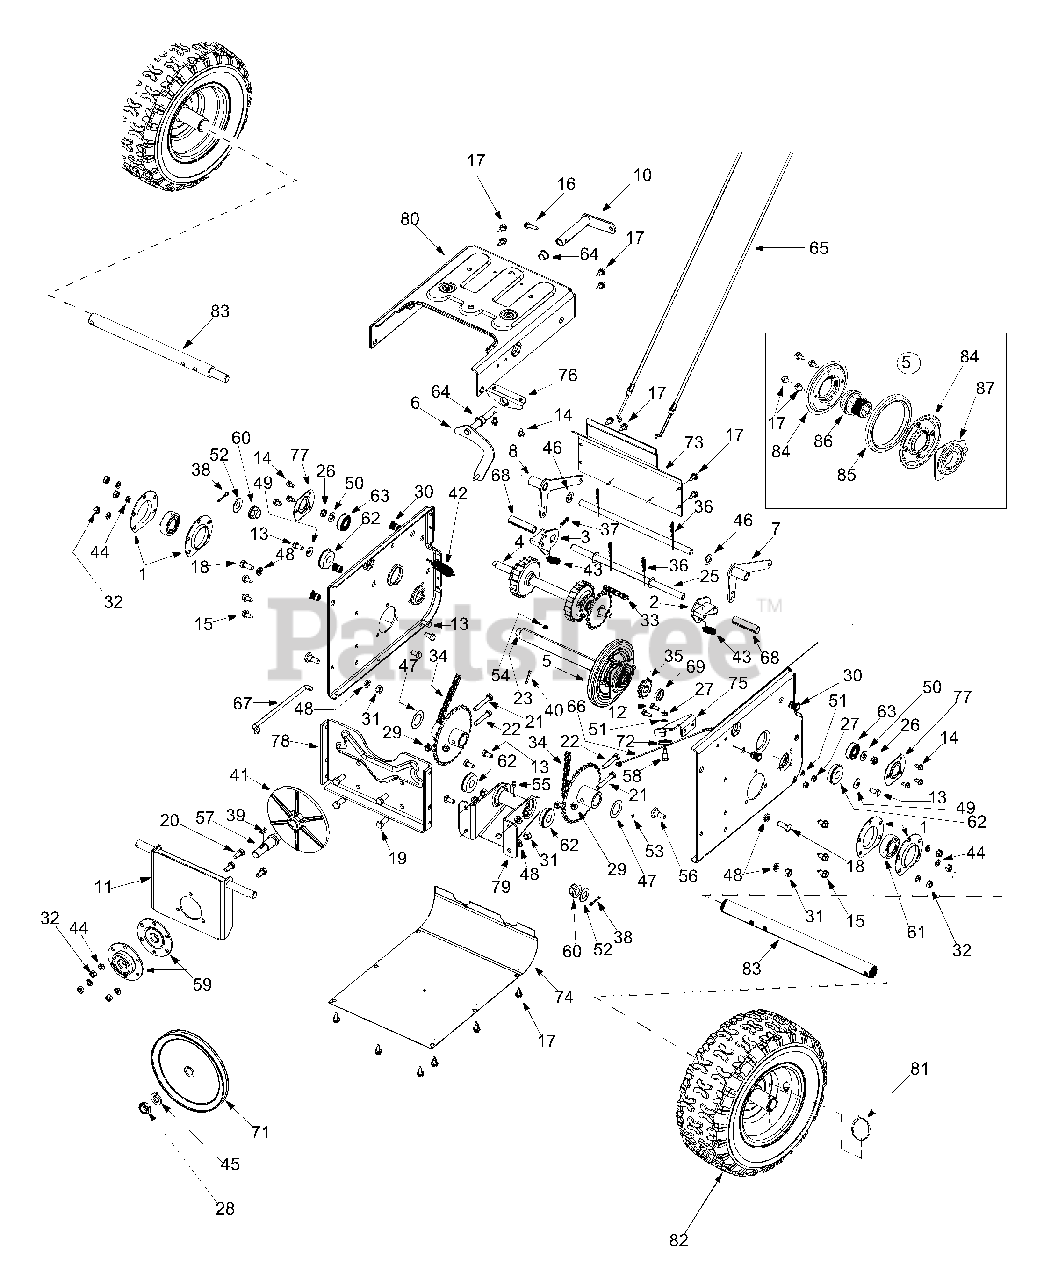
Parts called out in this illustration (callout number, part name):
1	Bearing Housing
2	Dogg Assembly LH
3	Dogg Assembly RH
4	Shift Assembly
5	Friction Wheel Assembly
6	Shift Rod Assembly
7	Actr. Bracket Assembly: Auger
13	Hex Screw 5/16-18 x .625"
14	TT Screw 1/4-20 x 0.5"
15	AB Screw 5/16-12 x 0.75"
16	TT Screw 1/4-20 x 1.0"
17	TT Screw 1/4-20 x .625"
18	Hex Screw 3/8-16 x .880"
19	Hex Screw 3/8-16 x .880"
20	Hex Screw 5/16-18 x 0.75"
21	Hex Screw 5/16-18 x 2.0"
22	Hex Screw 5/16-18 x 1.75"
23	Drive Shaft
24	Actr. Shaft
25	Actr. Shaft: Drive
26	Jam Nut
27	Hex Nut 1/4-28
28	Jam Nut
29	Lock Nut
30	Nut Insert
31	Hex Nut 3/8-16
32	Hex Nut 5/16-18
33	Chain: Endless
34	Chain
35	Sprocket
36	Hairpin Clip
37	Hairpin Clip
38	Cotter Pin
39	Key
40	Spring Pin
41	Drive Plate
42	Extension Spring
43	Extension Spring
44	Lock Washer 5/16
45	Lock Washer 5/8
46	Flat Washer .53 x .93 x .050
47	Flat Washer 1.030 x 1.620 x .030
48	Lock Washer
49	Bell Washer
50	Flat Washer .406 x .875 x .059
51	Lock Washer 1/4
52	Flat Washer .64 x 1.24 x .06
53	Grease
54	Lubricant
55	Lube Fitting: 3/16 Drive
56	Shoulder Screw
57	Spindle: drive Plate
58	C Screw 1/4-28 x .375"
59	Bearing Housing
60	Hex Flange Bearing
61	Bearing: Self-Aligning
62	Ball Bearing
63	Ball Bearing
64	Flange Bushing
65	Steering Cable
66	Idler Cable: Auger
67	Clutch Rod: Drive
68	Split Spacer
69	Spacer
70	Spacer
71	Drive Pulley
72	Cable Roller
83	Axle: Wheel
84	Friction Plate
85	Friction Wheel Rubber
86	Friction Wheel Hub
87	Friction Wheel Bearing
